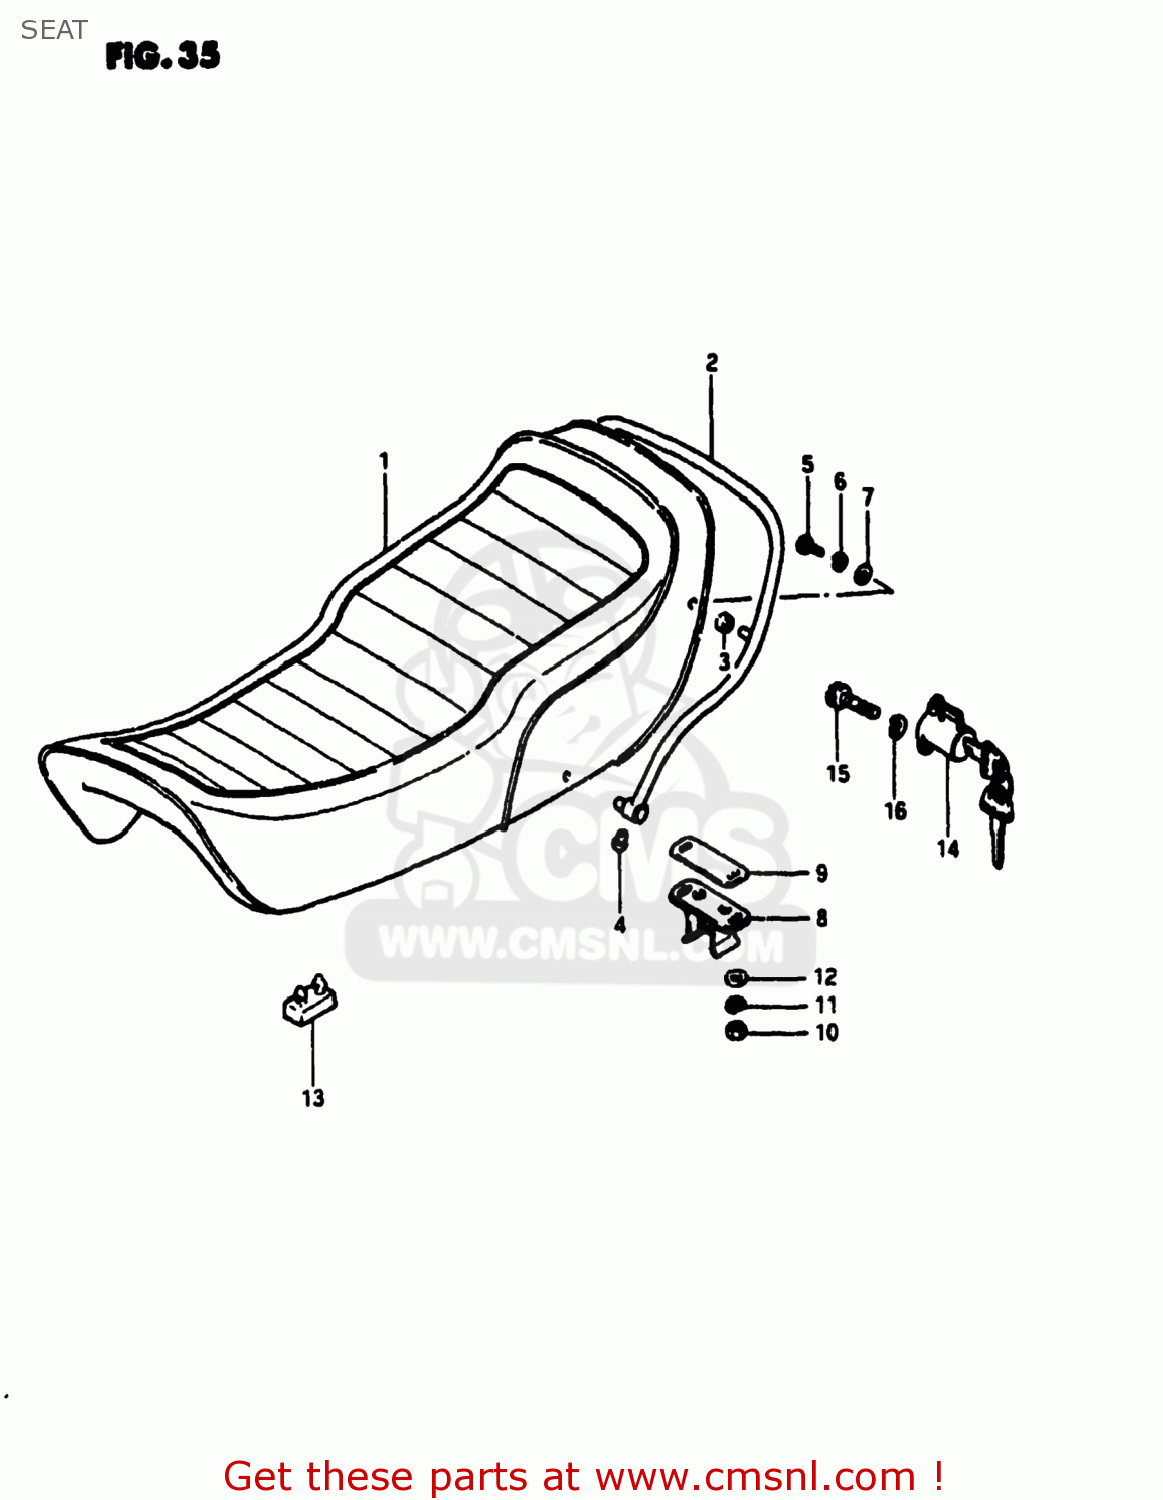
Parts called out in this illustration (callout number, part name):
1	SEAT ASSEMBLY
2	HANDLE,PILLION RIDER
3	CUSHION
4	END,SHEET HANDLE
5	BOLT
6	LOCK WASHER
7	WASHER
8	STRIKER, SEAT LOCK
9	SHIM,SEAT LOCK STRIKER
10	NUT 6MM
11	LOCK WASHER
12	WASHER
13	CUSHION
14	LOCK ASSEMBLY,HELMET
15	BOLT
16	LOCK WASHER
